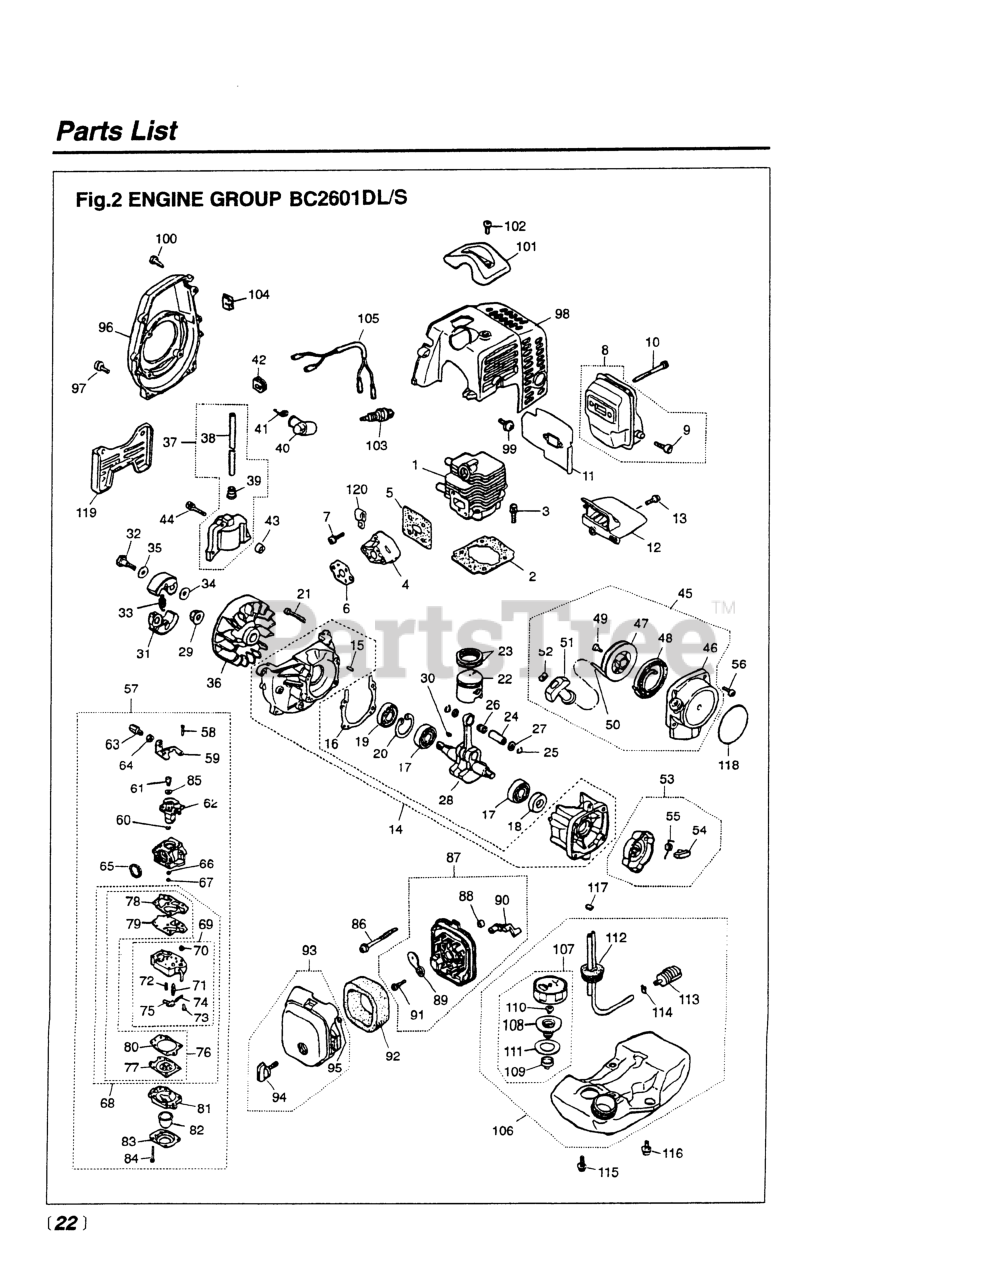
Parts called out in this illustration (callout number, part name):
1	CYLINDER
3	BOLT, M5 X 22
4	INSULATOR (USE -13163)
5	GASKET (RPLS -13120)
6	GASKET (REPLACES -13130)
7	SCREW, M5X20 (RPLS.1400-75510)
8	MUFFLER ASSY (RPLS 5501- )
9	ARRESTER (RPLS 5850-15140)
10	BOLT, M5 x 50
11	GASKET, MUFFLER (RPLS -15111)
13	SCREW, M4 X 16
14	CRANKCASE
15	PIN
16	GASKET (RPLS -21140)
17	BEARING
18	SEAL, OIL (RPLS 1100-21210)
19	SEAL, OIL (RPLS 1140-21220)
20	RING, SNAP, M28 x 1.2
21	BOLT, M5 X 30
22	PISTON
23	RING, PISTON
24	PIN, PISTON
25	RING, SNAP (RPLS 1101-41320)
27	WASHER
28	CRANKSHAFT (RPLS 1850-42000)
30	KEY
31	SHOE (RPLS 1100-51114)
32	BOLT
33	SPRING, CLUTCH (RPLS-51220)
34	WASHER, FLAT (USE 182303)
36	ROTOR
37	COIL ASSY (RPLS 5500-71200)
38	CORD
39	CAP
41	SPRING
42	GROMMET
43	SPACER (RPLS -71260)
44	BOLT
45	RECOIL ASSEMBLY
46	CASE
47	REEL
48	SPRING, SPIRAL
49	SCREW (RPLS -75150)
51	KNOB
52	PLATE, STOPPER
53	PULLEY ASSY (RPLS -75210)
54	RATCHET (RPLS 1850-75220)
55	SPRING, RETURN
56	SCREW, M4 X 16
57	CARBURETOR (WYJ-117)
58	SCREW
60	RING
61	SWIVEL
62	VALVE ASSY
63	SCREW, CABLE ADJUSTER
64	NUT, CABLE ADJUSTER
65	RING, PACKING
66	RING, O
67	JET
69	BODY, PUMP
70	SCREEN
71	VALVE, INLET
73	SCREW
74	PIN
75	LEVER
77	WASHER
78	GASKET, PUMP
79	DIAPHRAGM, PUMP
80	GASKET, DIAPHRAGM
81	BODY, PURGE
82	PUMP, PRIMING
83	COVER, PUMP
84	SCREW
85	WASHER
86	SCREW, M5 X 55
87	BODY-A (RPLS -82101)
88	SLEEVE
89	PLATE, CHOKE (RPLS-82130)
90	LEVER, CHOKE
91	SCREW (REPLACES 50030272)
92	ELEMENT
94	KNOB (RPLS -82220)
95	RING
96	COVER, FAN (RPLS-31110)
97	SCREW, M5X20 (RPLS.1400-75510)
98	COVER, ENGINE (RPLS -32111)
99	SCREW, M5 x 12
100	SCREW, HOUSING
101	GUARD, PLUG
102	SCREW,M5 X 14 (RPLS 1400-15510
105	CORD COMPLETE
109	HOLDER, CAP
110	VALVE (NLA WHEN OUT)
111	PACKING
112	PIPE COMPLETE
113	FILTER (RPLS 1850-85300)
114	CLIP (REPLACES 2841-31280)
115	SCREW
116	SCREW W/ WASHER
117	CLIP
118	LABEL (BC2601DL)
119	STAND
120	CLAMP
